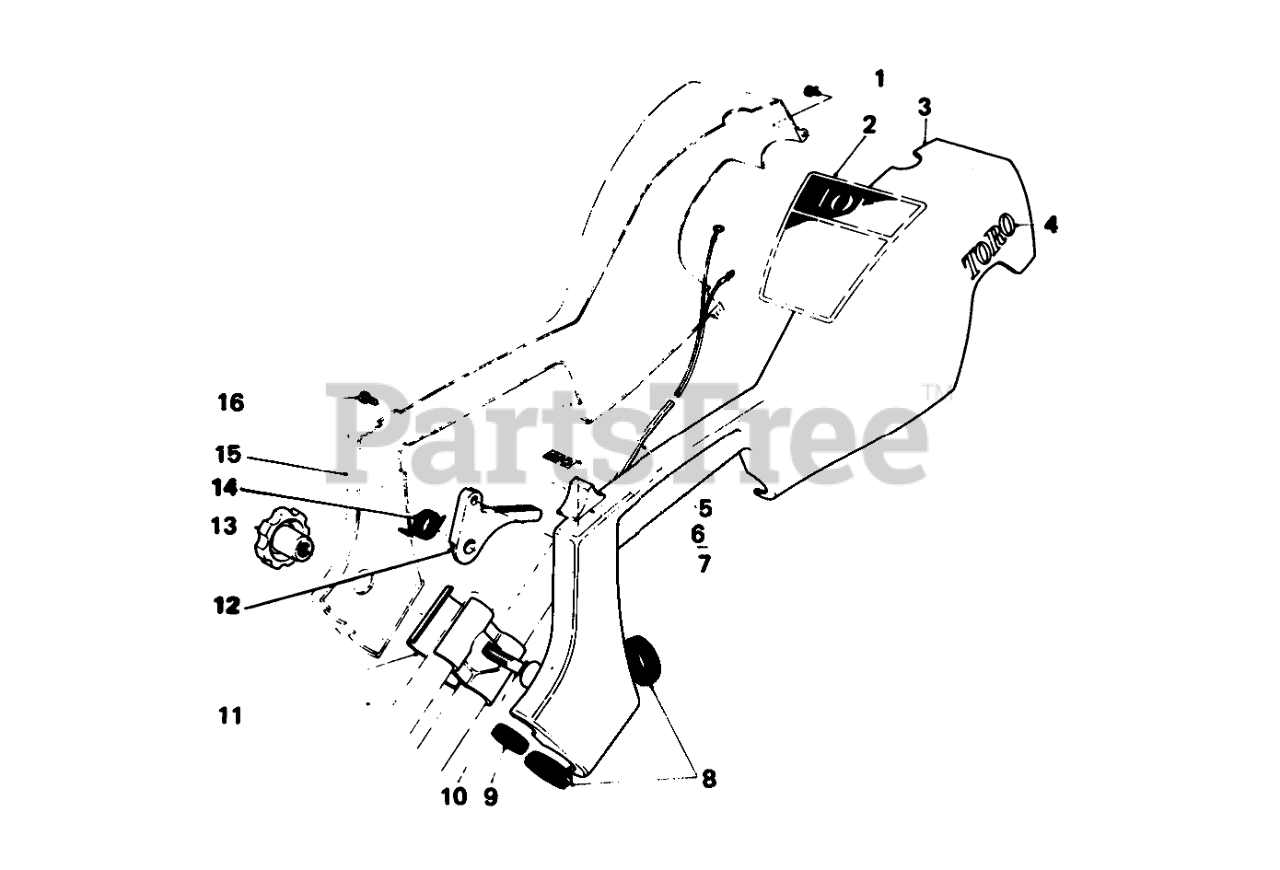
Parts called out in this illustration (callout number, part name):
2	Toro Decal Trimmer/Weeder
3	Engine Housing L.H.
4	DECAL - TORO
5	Wiring Harness
6	Decal Kill Switch
7	SWITCH COVER-BLACK
8	GROMMET
9	GROMMET
10	BOLT-CARR
11	Brkt.-Handle Support
12	Throttle Lever
14	Spring Torsion
15	Engine Housing R.H.
16	Screw
